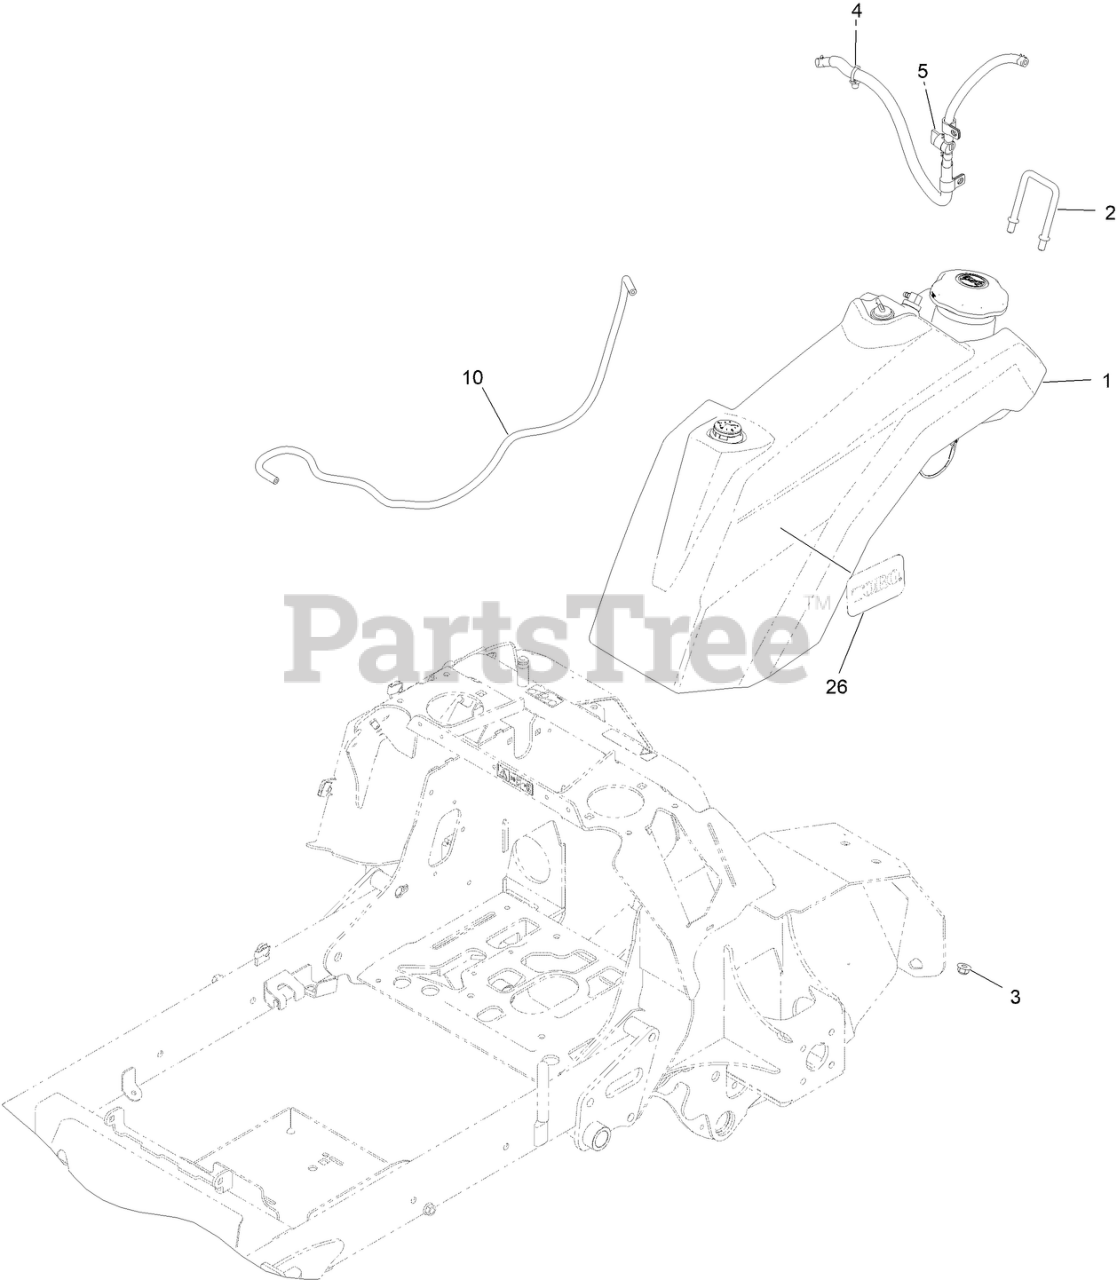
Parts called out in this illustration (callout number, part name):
1	ASM-FUEL TANK
2	CLAMP, TANK
3	NUT-HF, NI
4	CLIP-TIE
5	ASM-FUEL LINE VALVE
10	HOSE-FUEL
26	DECAL-TORO LOGO
